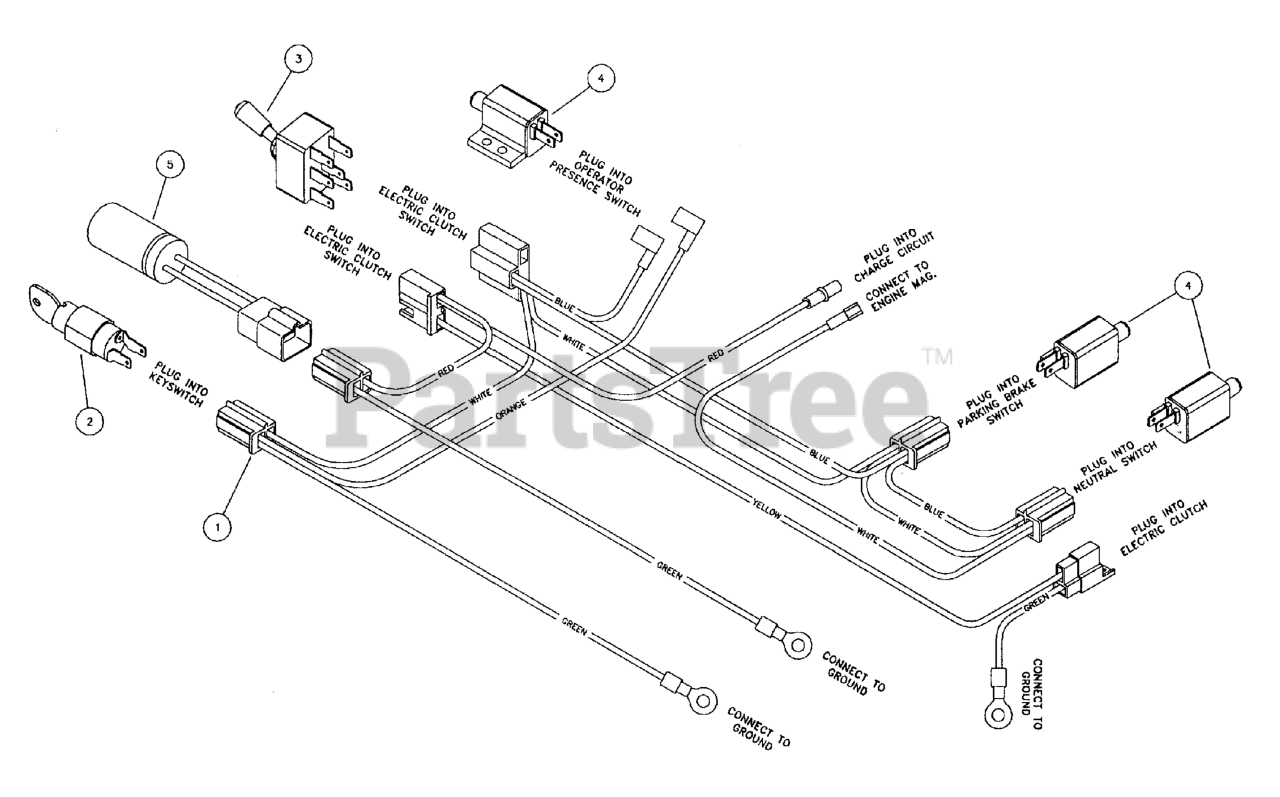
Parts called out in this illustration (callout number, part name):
1	DDSBV WIRING HARNESS
2	SWITCH, Ignition, Complete
3	SWITCH, Electric Clutch
4	SWITCH, PLUNGER, N.C.
5	DDSBV Capacitor Harness
